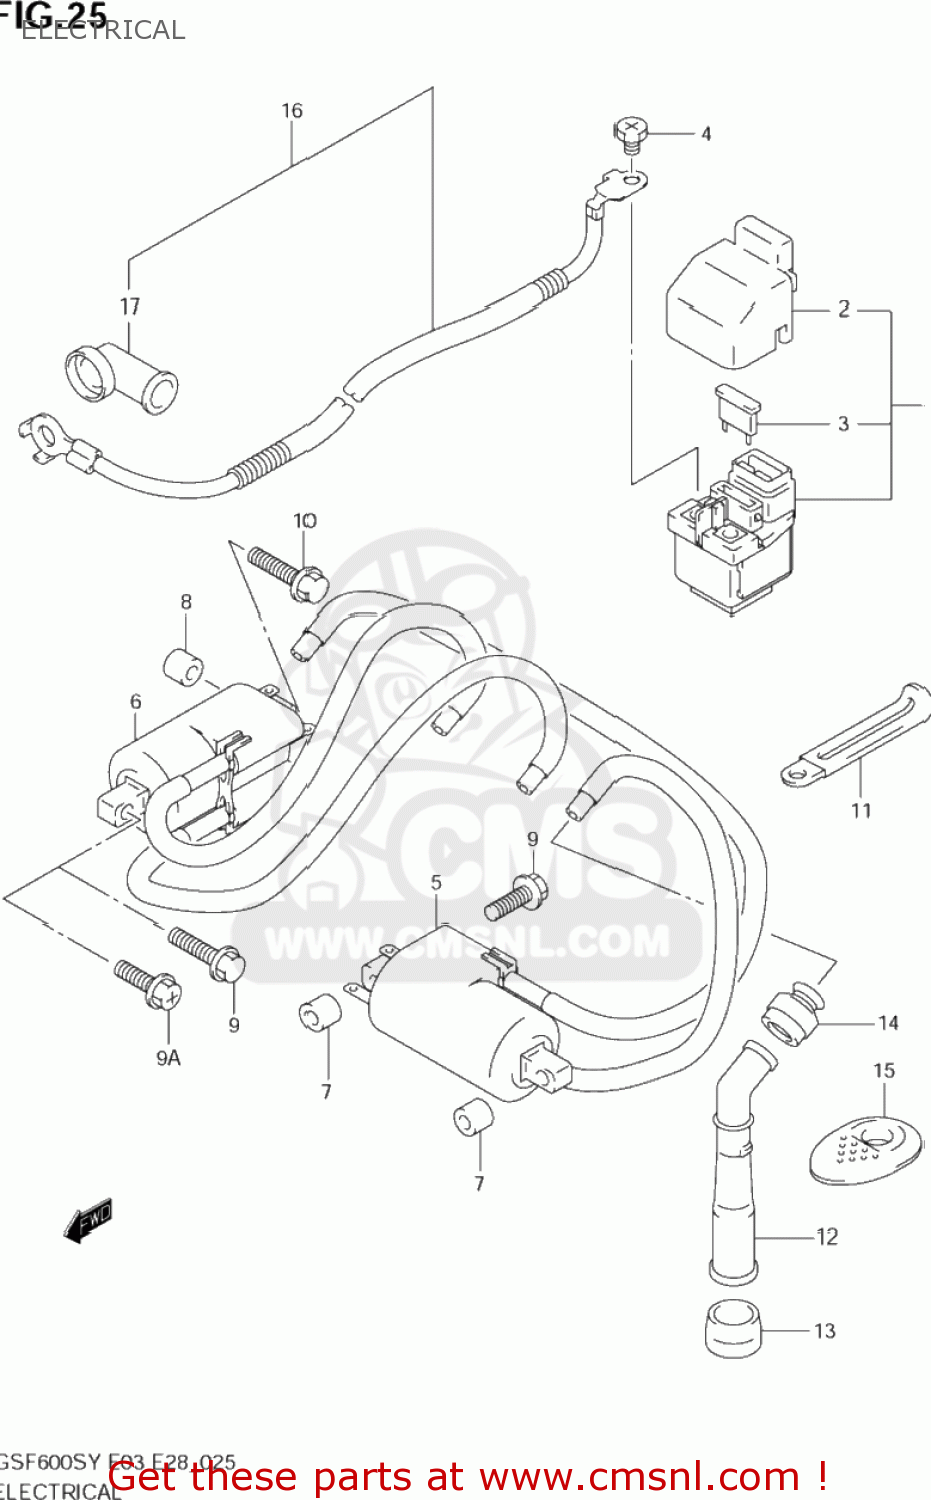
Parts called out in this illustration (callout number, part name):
1	RELAY ASSY,STARTING MOTOR
2	COVER,STARTER RELAY
3	FUSE(30A)
4	SCREW(6X8)
5	COIL ASSY,IGNITION
6	COIL ASSY,IGNITION
7	SPACER(6X12X10)
8	SPACER(6.4X10X18)
9	BOLT
9A	BOLT
10	BOLT
11	CLAMP(L:65)
12	CAP,SPARK PLUG
13	SEAL,SPARK PLUG CAP
14	SEAL,HIGH TENSION CORD
15	COVER,SPARK PLUG CAP
16	WIRE,STARTER MOTOR LEAD
17	CAP,STARTER MOTOR LEAD
